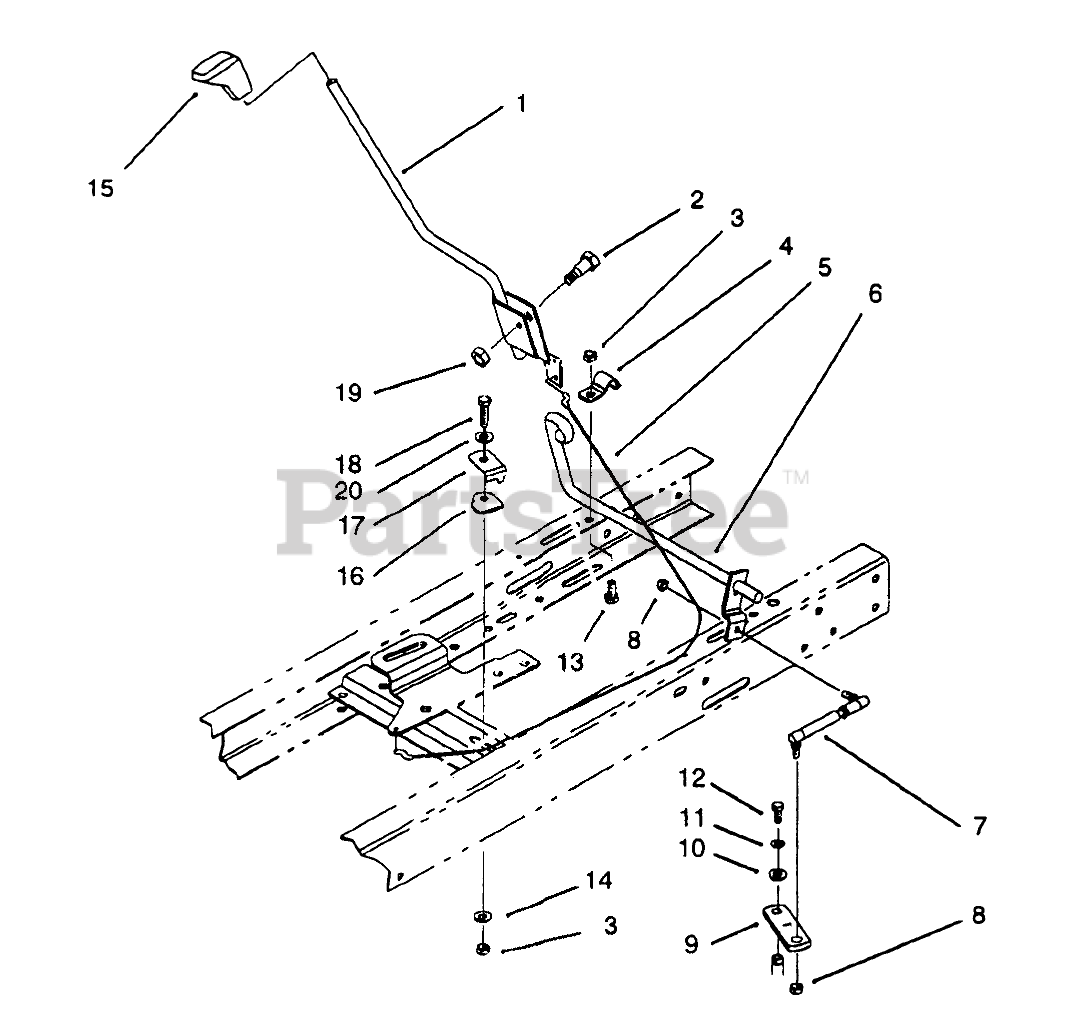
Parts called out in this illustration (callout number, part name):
1	Lever-Shift
2	SHOULDER BOLT
3	NUT-LOCK, NI
4	CLAMP-PIVOT, SHIFT
5	CABLE-CLUTCH
6	Pivot-Shift
7	TIE ROD, SHIFT
8	NUT-LOCK
9	LEVER-SHIFT
10	SPACER
11	WASHER-LOCK
12	SCREW-HH
13	SCREW-HH
14	WASHER-PLAIN
15	SHIFT KNOB
16	GUIDE-CABLE
17	KEEPER-CABLE
18	SCREW-CARR
19	NUT-LOCK, NI
20	WASHER-FLAT
